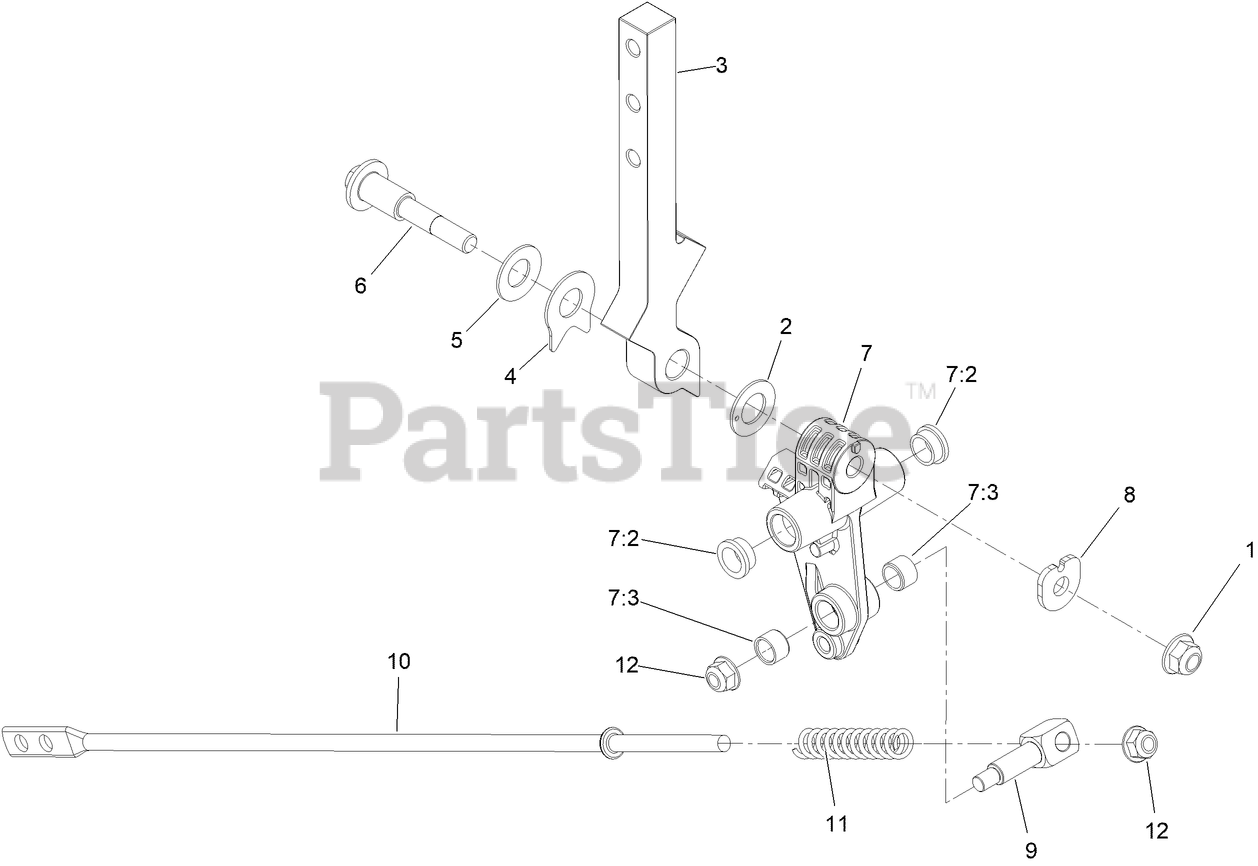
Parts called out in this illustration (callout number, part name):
1	NUT-HF, NI
2	WASHER-FRICTION
3	ARM-CONTROL
4	SPACER, ANTI-ROTATION
5	WASHER-BELLEVILLE
6	BOLT-PIVOT
7	ASM-CONTROL ARM
7:2	BUSHING
7:3	BUSHING-SLEEVE
8	SPACER-ACTUATOR
9	SWIVEL
10	LINK-CONTROL
11	SPRING-RETURN, NEUTRAL
12	NUT-HF, NI
